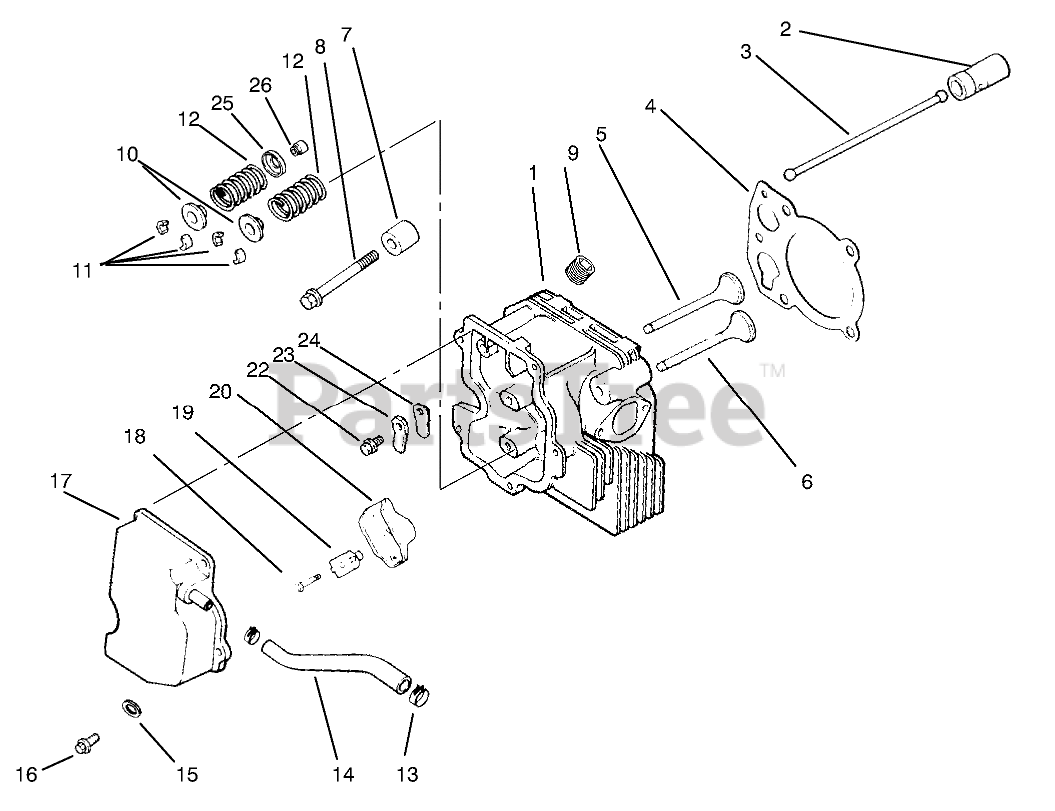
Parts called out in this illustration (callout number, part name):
1	Cylinder Head
2	Lifter-Valve
3	Rod-Push
4	Gasket-Cylinder Head
5	Valve-Intake STD
5	Valve-Intake .25
6	Valve-Exhaust STD
6	Valve-Exhaust .25
7	Spacer-Head Bolt
8	Screw M10x1.5x80
9	Plug
10	Cap-Spring, Valve
11	Retainer Kit
12	Spring-Valve
13	Clamp
14	Hose-Breather
15	Washer
16	Screw
17	Cover-Valve w/Nipple
19	Pivot-Rocker Arm
20	Arm-Rocker
22	Screw
23	Retainer-Reed
24	Reed-Breather
25	Retainer-Spring
26	Seal-Stem, Valve
